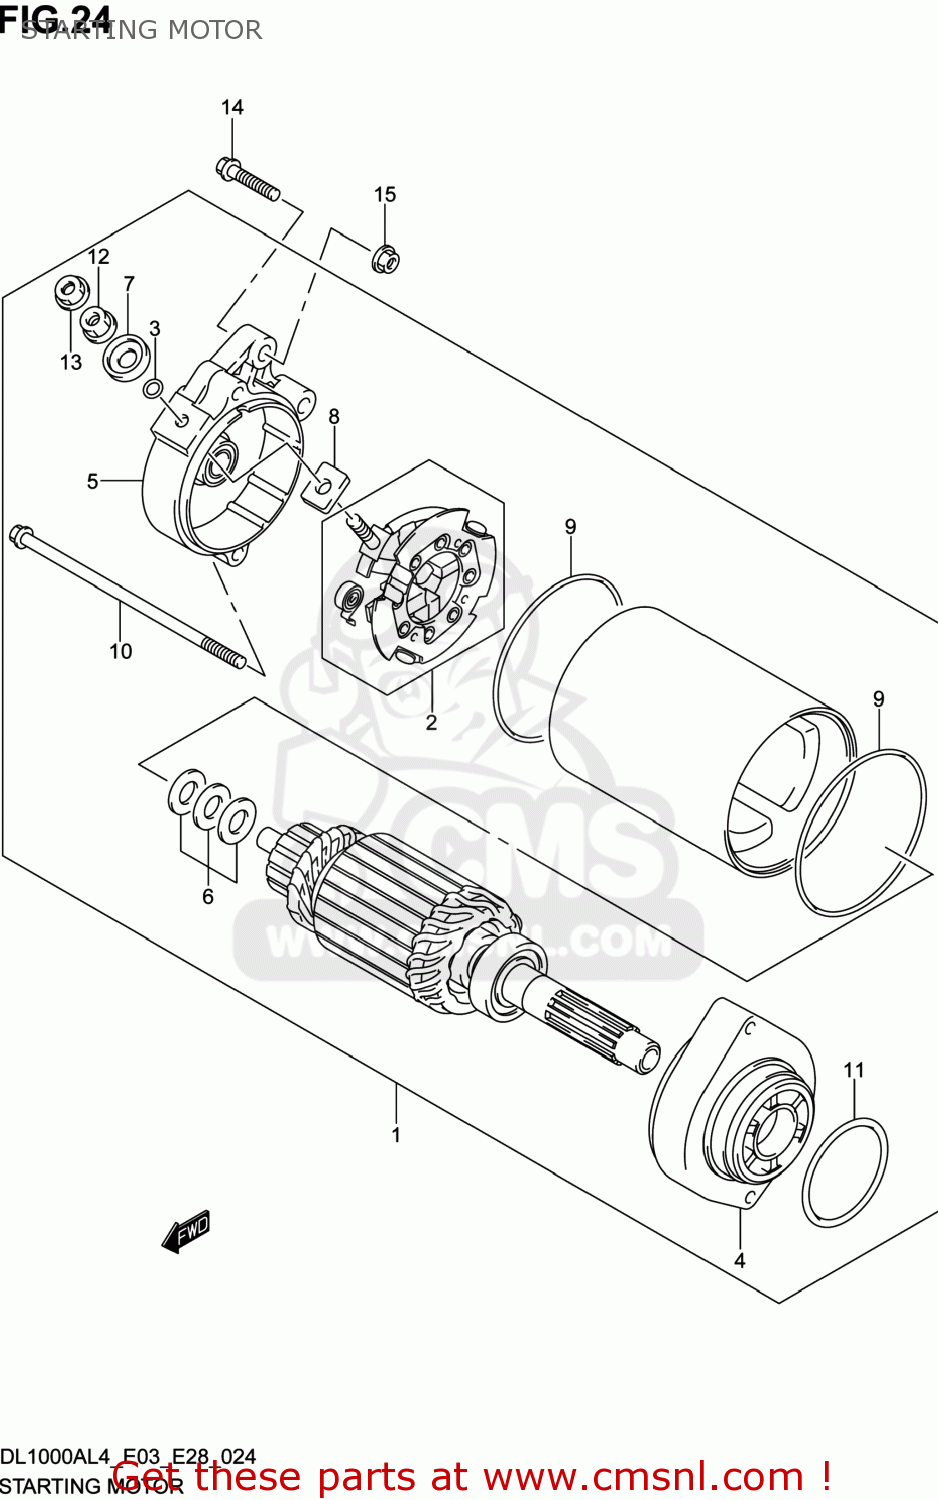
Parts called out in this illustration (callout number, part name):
1	MOTOR ASSY,STARTING
2	HOLDER SET,BRUSH
3	O RING
4	HOUSING ASSY
5	FRAME ASSY
6	SHIM SET,STARTING MOTOR
7	BUSHING
8	BUSHING
9	O RING
10	BOLT
11	O RING
12	NUT
13	NUT
14	BOLT
15	NUT
